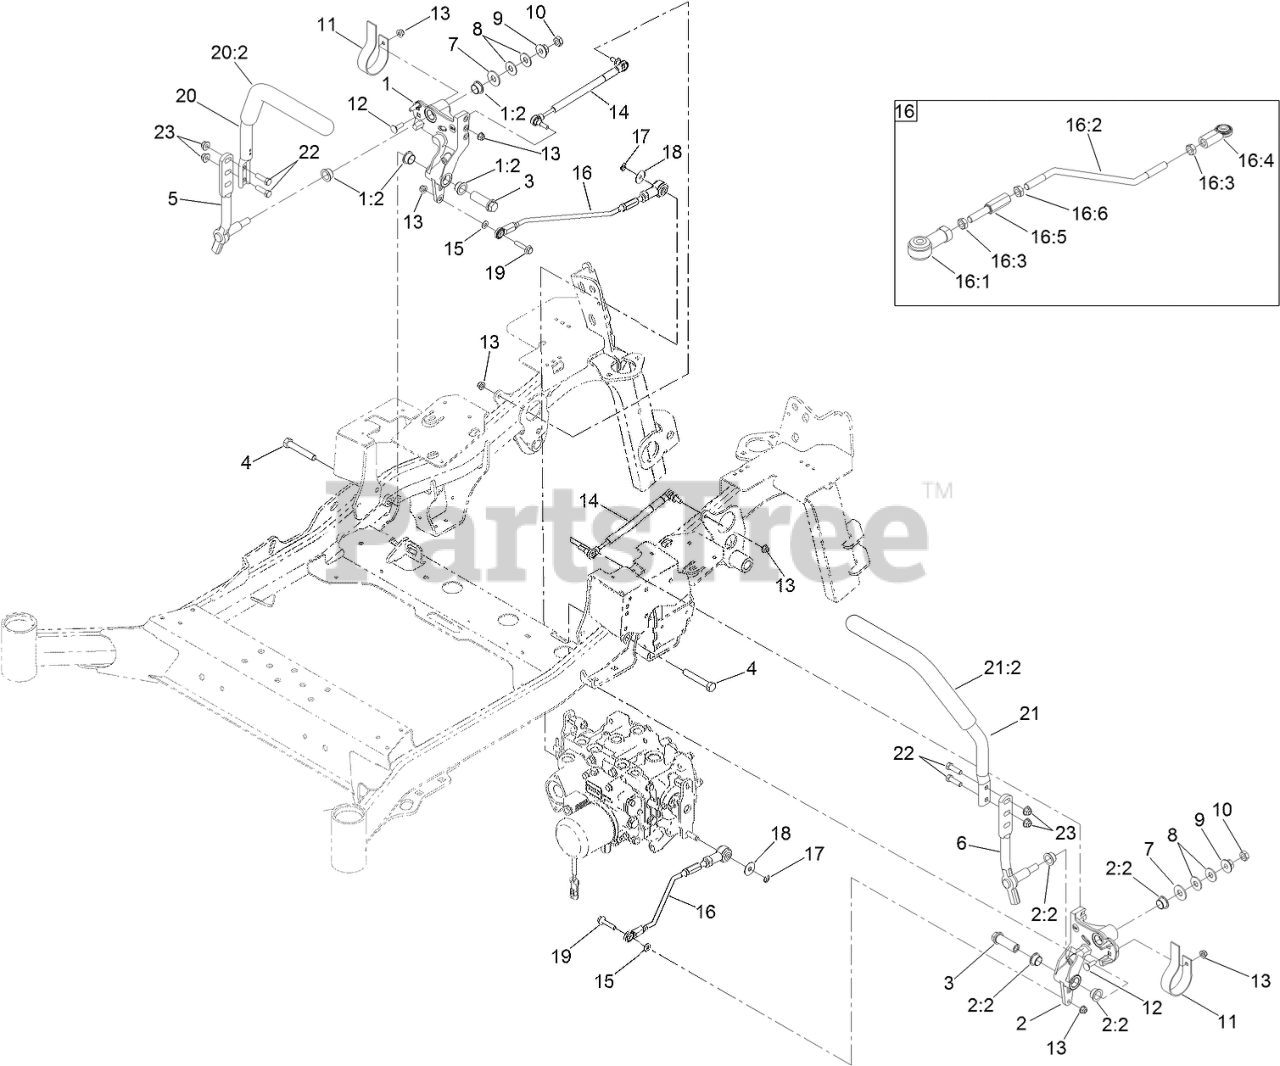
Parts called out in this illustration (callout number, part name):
1	RH MOTION CONTROL AND BUSHING ASM
1:2	BUSHING-FLANGE
2	LH MOTION CONTROL AND BUSHING ASM
2:2	BUSHING-FLANGE
3	HUB-THREADED
4	SCREW-HH
5	LEVER-CONTROL MOTION, RH
6	LEVER-CONTROL MOTION, LH
7	WASHER-FLAT
8	WASHER-SPRING
10	NUT-JAM
11	SPRING-LEAF
12	BOLT-CARR
13	NUT-HF, NI
14	DAMPER-CONTROL, MOTION
15	WASHER-PLAIN
16	FRONT LINKAGE ROD ASM
16:1	END-ROD, ISOLATED
16:2	ROD-LINKAGE, REAR
16:3	NUT-HJ
16:4	JOINT-BALL, END
16:5	ROD-ADJUSTMENT
16:6	NUT-HEX JAM, LH
17	RING-RETAINING
18	WASHER-PLAIN
19	SCREW-HHF
20	RH STEERING HANDLE ASM
20:2	GRIP-LEVER, CONTROL
21	LH STEERING HANDLE ASM
21:2	GRIP-LEVER, CONTROL
22	SCREW-HH
23	NUT-HF, NI
